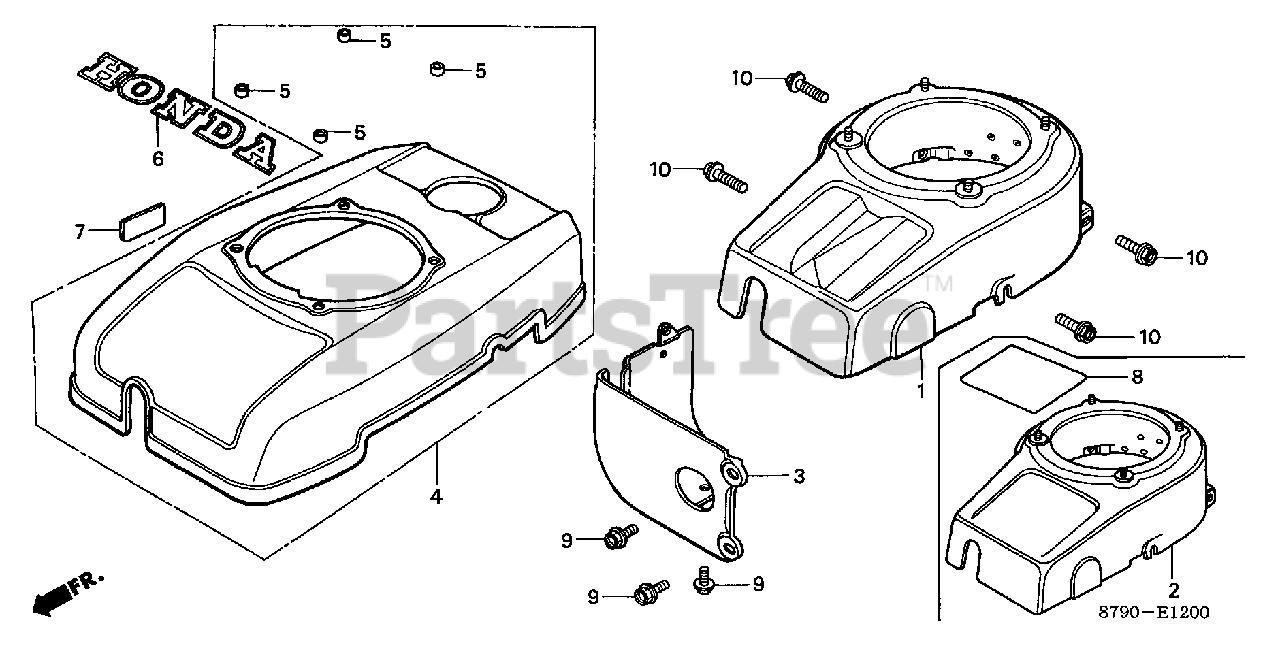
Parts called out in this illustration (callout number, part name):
2	COVER, FAN *A14* (SNAPPER WHITE)
3	COVER, SIDE
7	LABEL, COMPLIANCE
8	PLATE, DESCRIPTION
9	BOLT, FLANGE (6X12)
10	BOLT, FLANGE (6X16)
